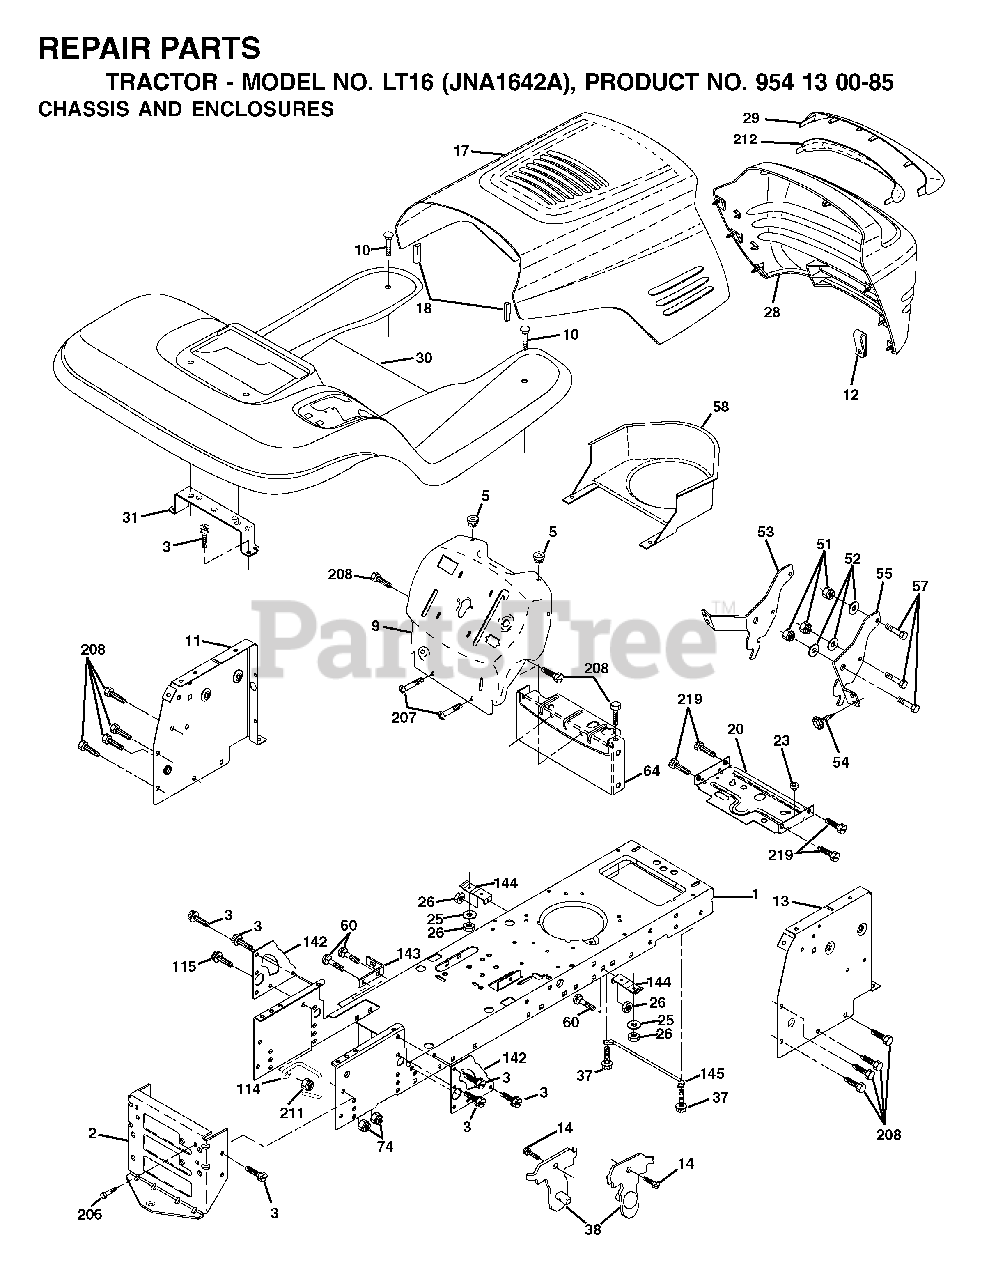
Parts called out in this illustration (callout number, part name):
1	CHASSIS STAMPING
2	DRAWBAR, 12GA
3	SCREW 3/8-16X3/4
5	BUMPER.RUBBER.HOOD
10	BOLT D
11	PANEL.DASH.LH.LTX
13	PANEL ASM, DASH RH
18	BUMPER HOOD T
20	PLATE MTG.BATTERY/FUEL TANK
23	GROMMET T
25	WASHER
26	NUT
28	GRILL/LENS ASM.
38	BRACKET.ASM.PIVOT.MOWER.REAR
51	LOCKNUT
53	BRACKET.GRILLE.LH
57	BOLT
58	AIR DUCT P/L/LT
60	BOLT D
64	DASH LOWER
74	LOCKNUT
115	SCREW.3/8-16
142	PLATE REINFORCEMENT
143	BRACKET, SWAY BAR
144	BRKT, FOOT REST
145	ROD PIVOT CHASSIS/HOOD
206	SHOULDER BOLT 5/16-18TT
207	SCREW, 5/16-18 X 1/2
208	SCREW 3/8-16X1/2
211	NUT
219	SCREW
